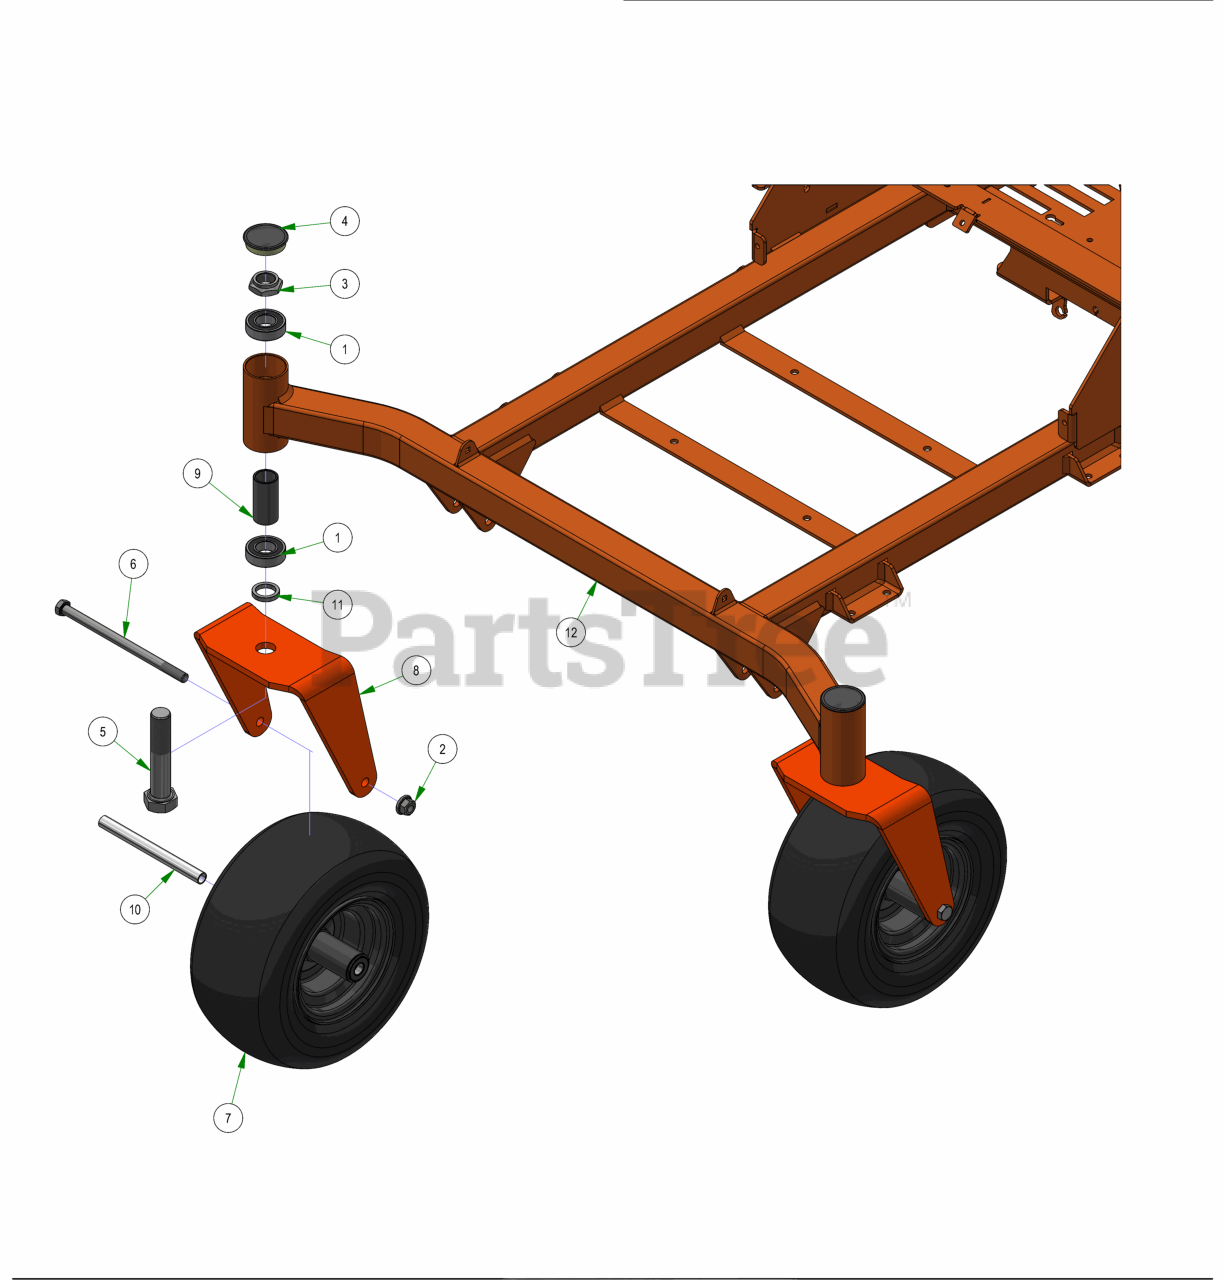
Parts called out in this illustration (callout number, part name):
1	1641 BEARING W/2 CONTACT RUBBER SEALS
2	1/2-13 NYLON INSERT FLANGE LOCKNUT ZINC
3	1"-14 NYLON INSERT JAM LOCKNUT ZINC
4	2017 Bearing Cover
5	1"-14 X 5 HEX CAP SCREW (GR.8) ZINC YELLOW
6	1/2-13 X 8-1/2 HEX CAP SCREW (GR.5) ZINC
7	12x6x6 Front Tire & Black Wheel Assembly
8	2017 ZT Front Fork
9	2016 Front Bearing Spacer
10	Front Wheel Spanner
11	1.02 ID X 1.38 OD X .250 THK SPACER ZINC
12	2025 MZ-Avenger 54-60 Frame
